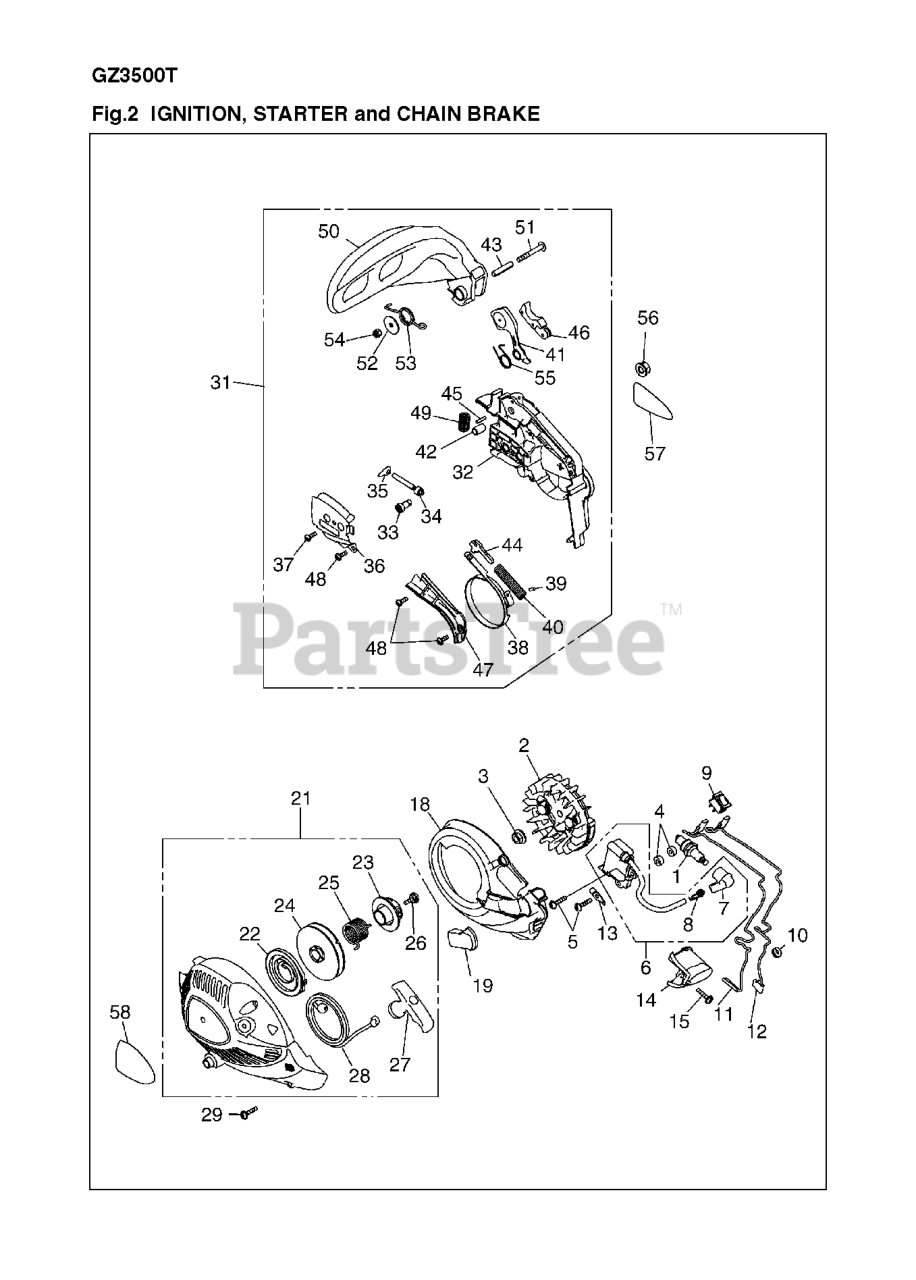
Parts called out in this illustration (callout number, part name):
1	SPARK PLUG (CMR6H)
2	ROTOR ASSY
3	NUT
4	SPACER
5	BOLT TORX 09
6	COIL COMP
6	COIL ASSY
7	CAP
8	SPRING
9	SWITCH
11	CORD, SWITCH
12	CORD, EARTH
13	TERMINAL
14	COVER PLUG
18	COVER FAN
19	GUIDE, DF (GZ3500T)
21	RECOIL ASSY
22	SPRING ASSY
23	CAM, PLATE
31	BRAKE ASSY
32	COVER CHAIN (GZ3500T)
34	SCREW
37	SCREW
38	BAND
39	ROLLER
40	SPRING
42	SPACER
43	SPACER, INNER
44	ARM
45	ROLLER
46	BRAKE LEVER
47	COVER BRAKE
48	SCREW
51	SCREW
52	WASHER
53	RETURN SPRING
55	SPRING
56	NUT
